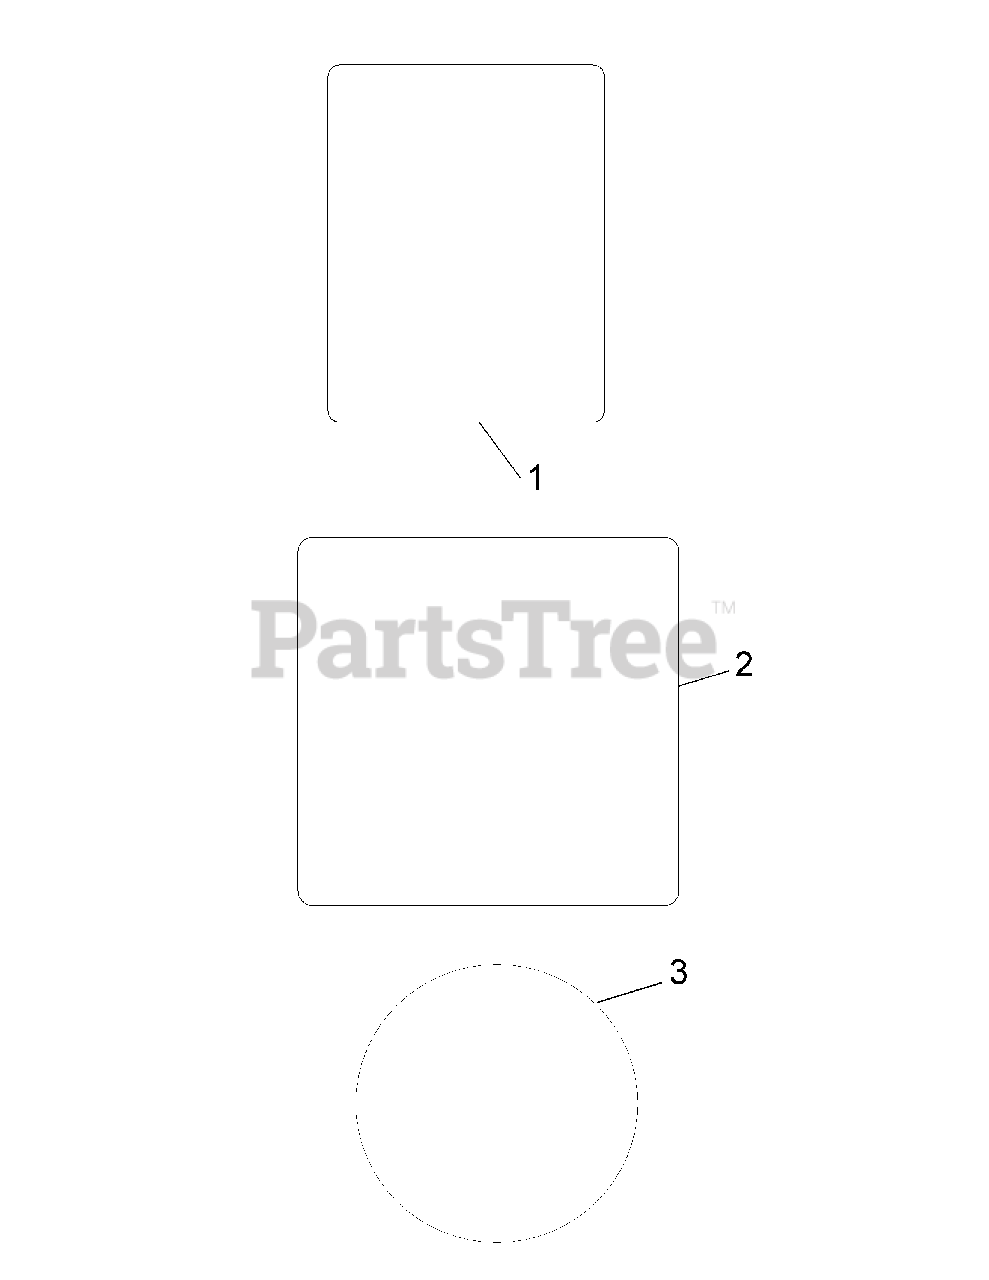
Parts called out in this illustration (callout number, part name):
1	Clear Laminate Decal
2	HDAC 747cc/CV-CH732 Decal
3	Grass Screen Decal
